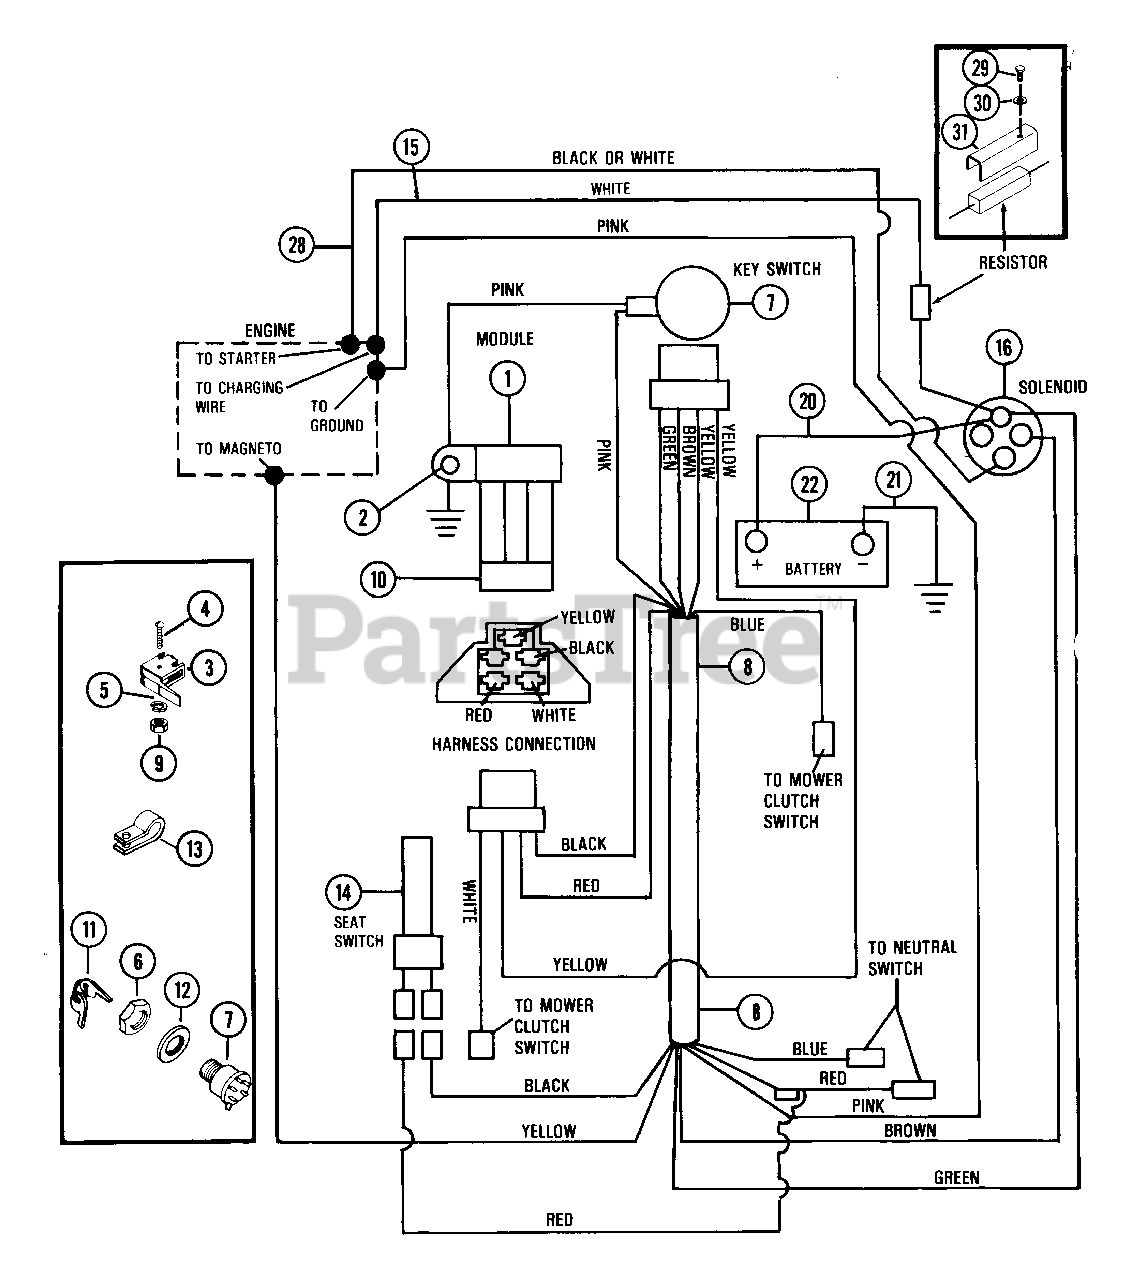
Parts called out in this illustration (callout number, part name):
1	MODULE
2	SCR-TAP 10-12X.50 CRPH PL A
3	SWITCH INTERLOCK
4	SCR-MCH 10-24X1.00 SLRH PL
5	WSHR-LK 10X.047 MED PL
6	NUT .625-32 ALUM
7	IGNITION SWITCH ASSEMBLY
8	WIRE HARNESS
9	NUT-HEX 10-24 PL
10	CONNECTOR
11	KEYS
12	WSHR-LK-INT .625X.045 PL
14	SWITCH SEAT
15	CHARGING WIRE
16	SOLENOID
20	GROUND CABLE .25X13.00X.31
21	GROUND CABLE .25X13.00X.31
22	BATTERY
23	BATTERY TRAY
24	RUBBER PAD
25	BATTERY STRAP
26	HOOK
27	SCR-TAP .312-18X.50 HWH PL TR
28	GROUND CABLE
29	SCR-TAP 10-16X1.0 SLHP PL AB
30	WSHR-FL-STL .250X.562X.049 PL
32	WSHR-LK .312X.097 PL HVY
33	NUT-JAM .312-24 PL
34	WSHR-LK 10X.047 MED PL
35	NUT 10-32 PL
36	NUT-HEX .250-20 PL
37	WSHR-LK-INT .313X.030 PL
38	BLT-RDHDSQNK .25-20X.75 GR5PL
